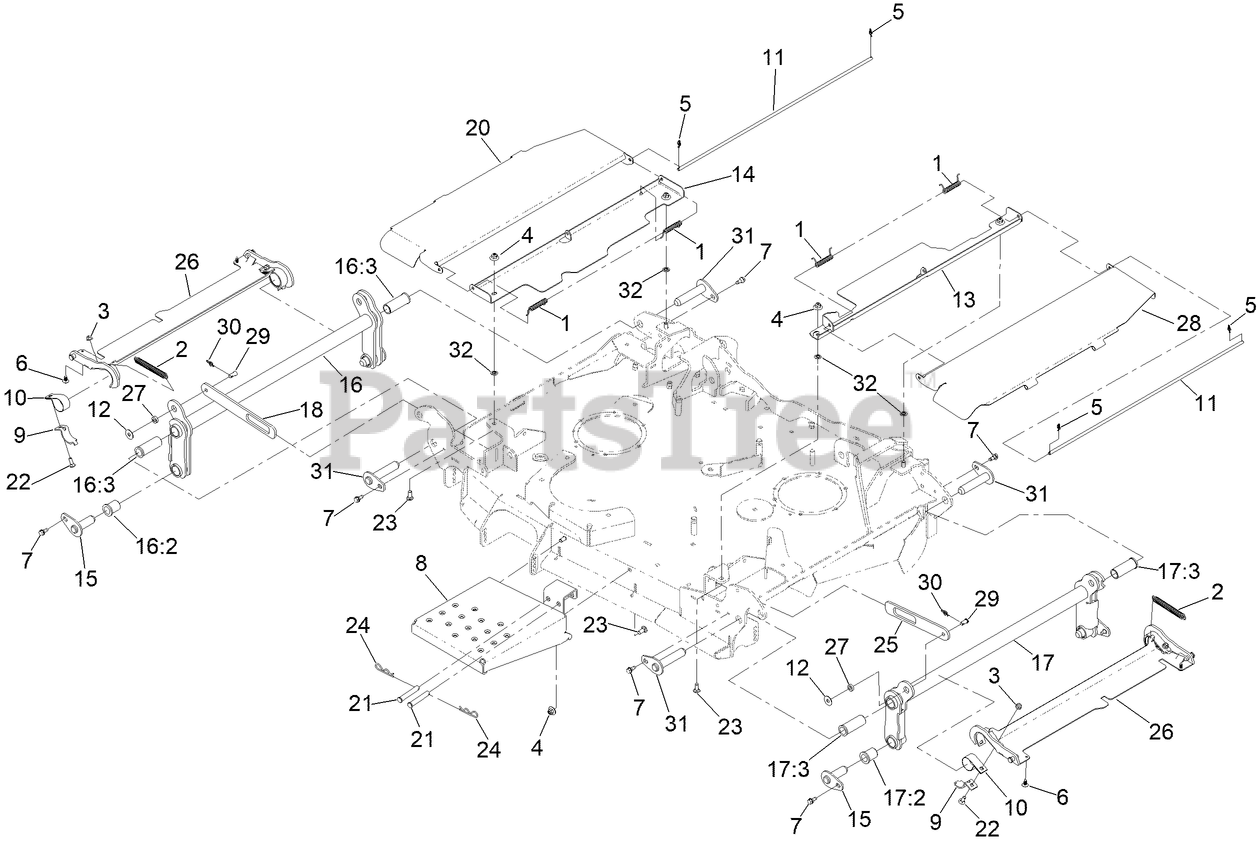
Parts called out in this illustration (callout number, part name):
1	SPRING-TORSION
2	SPRING
3	NUT-HF, NI
4	NUT-FLANGE, NI
5	PIN-COTTER, LOCKING
6	PLUG-PLASTIC
7	SCREW-SHOULDER
8	PLATE-DECK STEP
9	PLATE-RETAINER, BEARING
10	BEARING-STRAP, NYLON
11	COVER-ROD, PIVOT
12	WASHER
13	SHIELD-CENTER, LH
14	SHIELD-CENTER, RH
15	ASM-DECK PIN
16	ASM-RH FOLD ARM
16:2	BUSHING-FLANGED
16:3	BUSHING-FLANGE
17	ASM-LH FOLD ARM
17:2	BUSHING-FLANGED
17:3	BUSHING-FLANGE
18	STRAP-RH FLAG
20	PANEL-SHIELD HINGE, RH
21	PIN-CLEVIS
22	SCREW-CARR
23	BOLT-CARR
24	PIN-HAIR
25	STRAP-LH FLAG
26	ASM-WING COVER, [RED]
27	BUSHING
28	PANEL-SHIELD HINGE, LH
29	PIN-CLEVIS
30	PIN-COTTER, LOCKING
31	ASM-DECK PIN
32	NUT-PUSH
